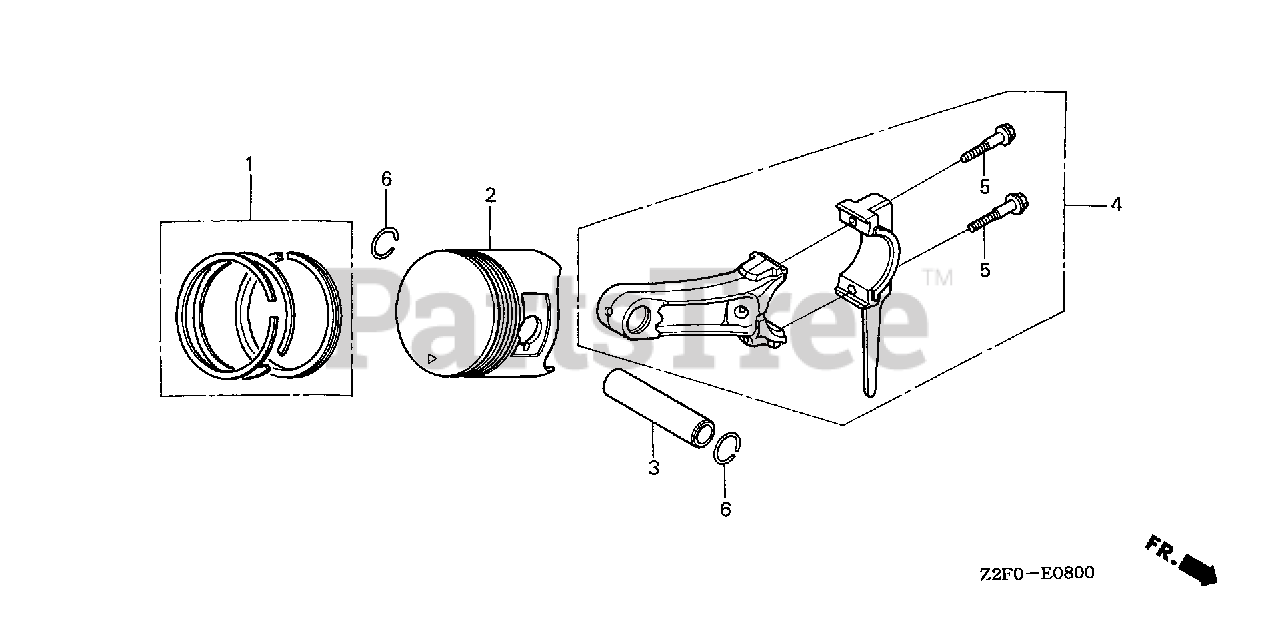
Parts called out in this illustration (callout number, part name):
1	RING SET, PISTON (STD) (TEIKOKU)
1	RING SET, PISTON (STD) (NIPPON)
1	RING SET, PISTON (STD) (TPR)
1	RING SET, PISTON (0.25) (TEIKOKU)
1	RING SET, PISTON (0.25) (NIPPON)
1	RING SET, PISTON (0.25) (TPR)
1	RING SET, PISTON (0.50) (TEIKOKU)
1	RING SET, PISTON (0.50) (NIPPON)
1	RING SET, PISTON (0.50) (TPR)
1	RING SET, PISTON (0.75) (TEIKOKU)
1	RING SET, PISTON (0.75) (NIPPON)
1	RING SET, PISTON (0.75) (TPR)
2	PISTON (STD)
2	PISTON (0.25)
2	PISTON (0.50)
2	PISTON (0.75)
3	PIN, PISTON
4	ROD ASSY., CONNECTING (STD)
4	ROD ASSY., CONNECTING (TH)
5	BOLT, CONNECTING ROD
6	CLIP, PISTON PIN (18MM)
